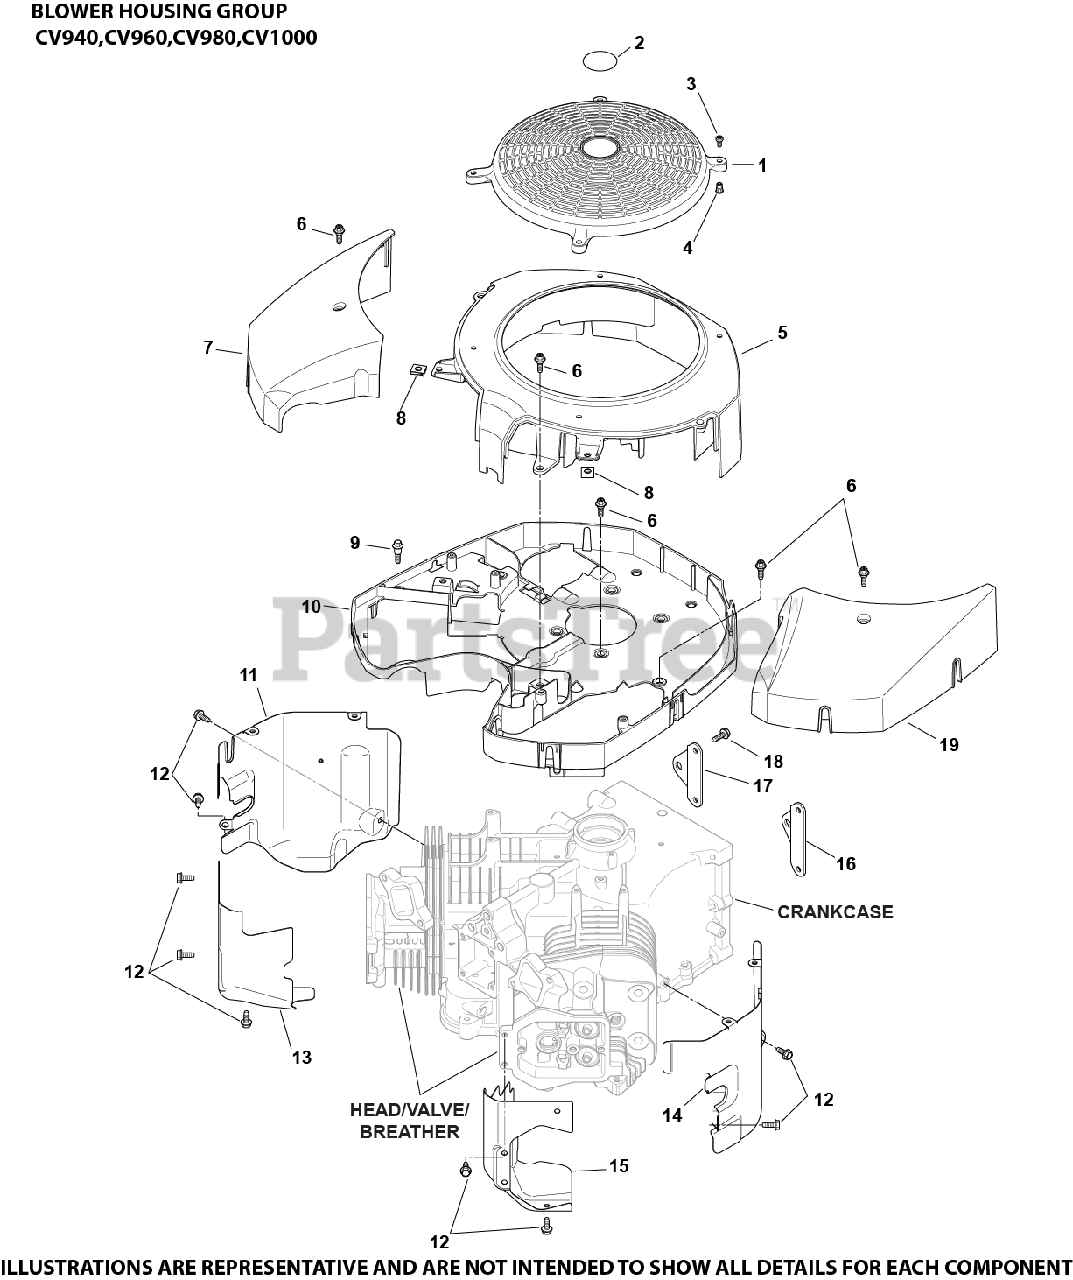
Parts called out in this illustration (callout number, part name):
1	KIT, FIXED GUARD
2	DECAL, GRASS SCREEN USE 24 113 499-S
3	SCREW, LBD SCKT PAN M5X0.8X10
4	INSERT, THREADED
5	HOUSING, BLOWER - (#6202707S)
6	SCREW, SHD THD FRM
7	SHROUD, #1 CYLINDER
8	CLIP, BAFFLE MOUNTING USE 25 154 37-S
9	SCREW, SHD THD FRM M6X1X26
10	SHROUD, BACKING USE 62 424 19-S
11	BAFFLE, CYL BARREL #1 SIDE
12	SCREW, THREAD FORMING
13	BAFFLE, VALLEY #1 SIDE
14	BAFFLE CYL BARREL #2 SIDE
15	BAFFLE VALLEY #2 SIDE
16	STRAP, LIFTING
18	SCREW, THREAD FORMING
19	SHROUD, #2 CYLINDER
